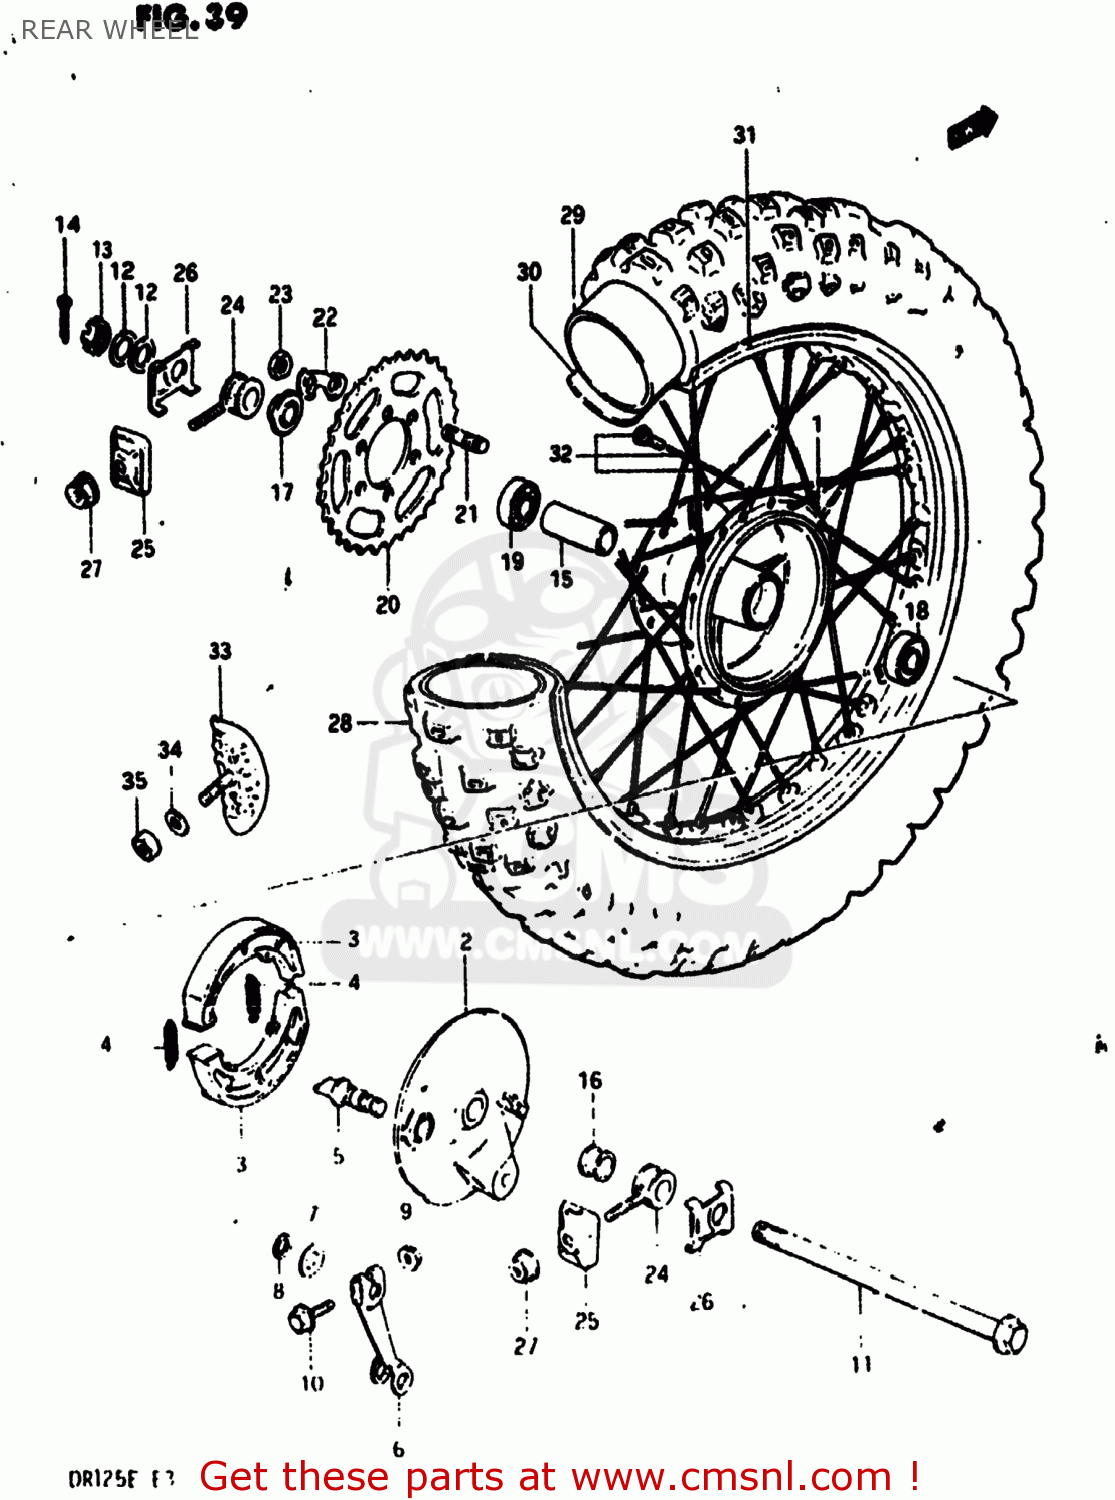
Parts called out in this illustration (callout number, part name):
1	HUB,REAR WHEEL
2	PANEL,RR BRAKE ANCHOR
3	SHOE,BRAKE
4	SPRING(L:34)
5	CAM,FRONT BRAKE
6	LEVER,RR BRAKE CAM
7	WASHER (14.5X22X1.6)
8	O-RING (D:2.4 ID:13.8)
9	NUT
10	BOLT
11	AXLE,REAR
12	WASHER
13	NUT
14	COTTER PIN
15	SPACER(15.3X21.7X107.5)
16	SPACER,RR AXLE,R
17	SPACER,REAR AXLE,LEFT
18	BEARING
19	BEARING
20	SPROCKET,RR(NT:47)
21	BOLT,STUD
22	WASHER
23	NUT
24	ADJUSTER,CHAIN
25	PLATE,CHAIN ADJUSTER
26	WASHER,CHAIN ADJUSTER GUIDE
27	NUT
28	TIRE
29	TUBE 3.50-17 089-432MM
30	PROTECTOR,WHEEL,INNER
31	RIM,REAR WHEEL (1.85-17 A)
32	SPOKE SET,REAR
33	STOPPER,BEAD
34	WASHER
35	NUT
